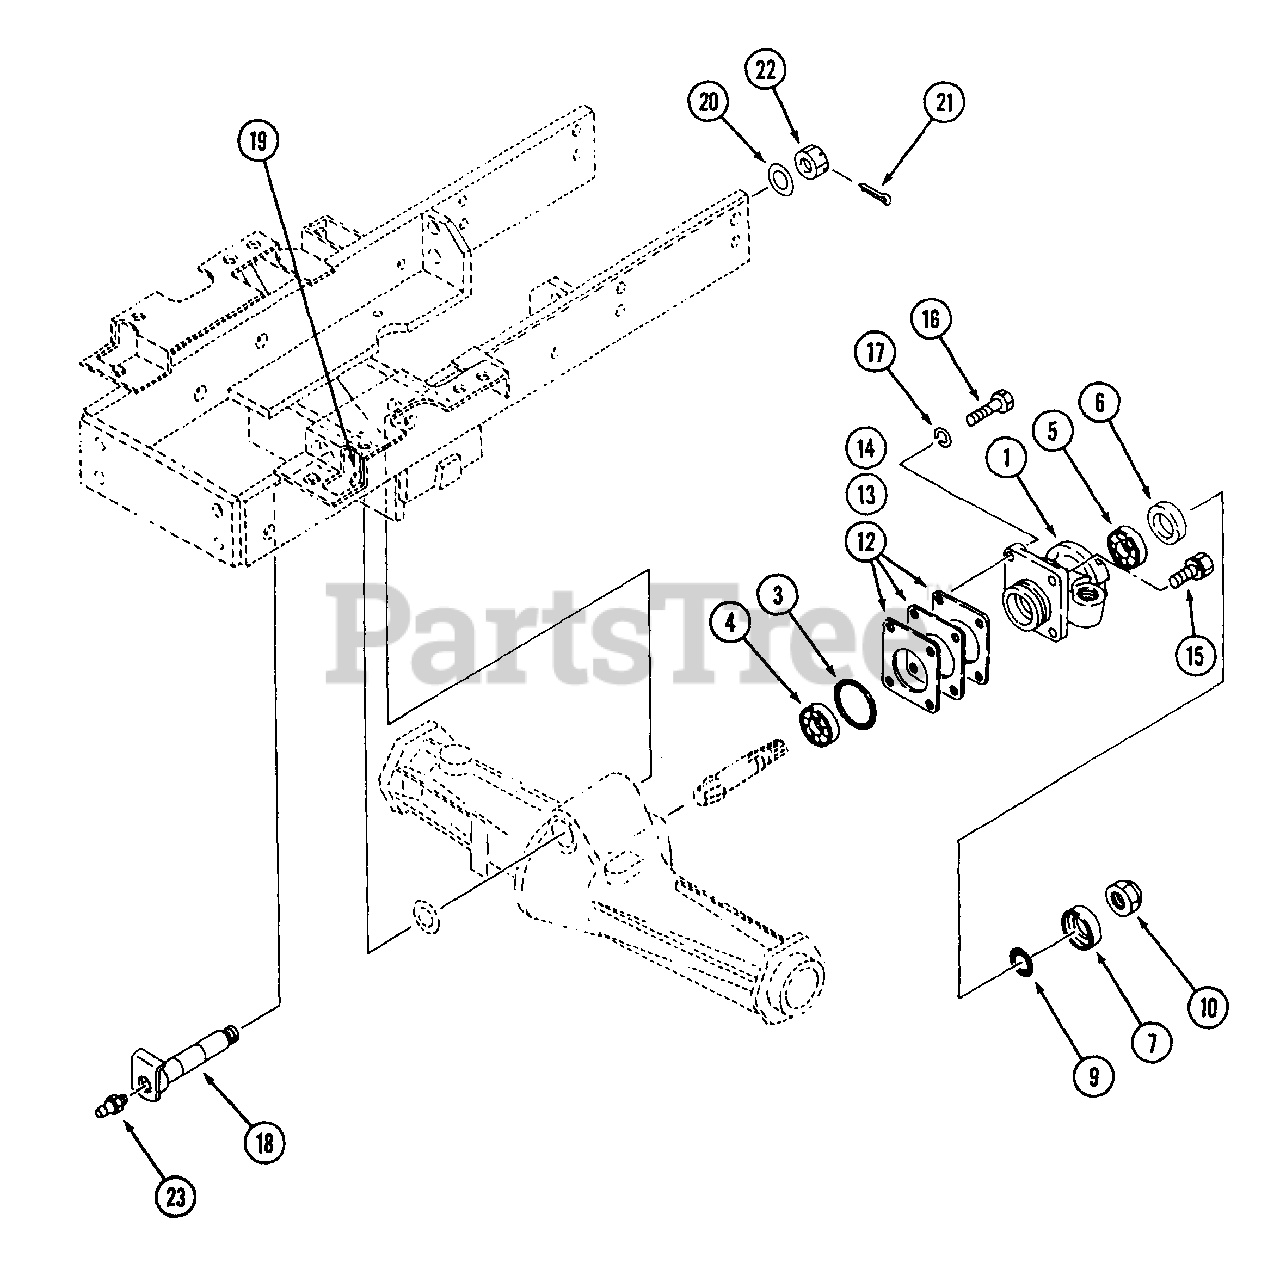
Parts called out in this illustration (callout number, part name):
18	Pin, Center
19	Washer
23	Nipple, Grease
